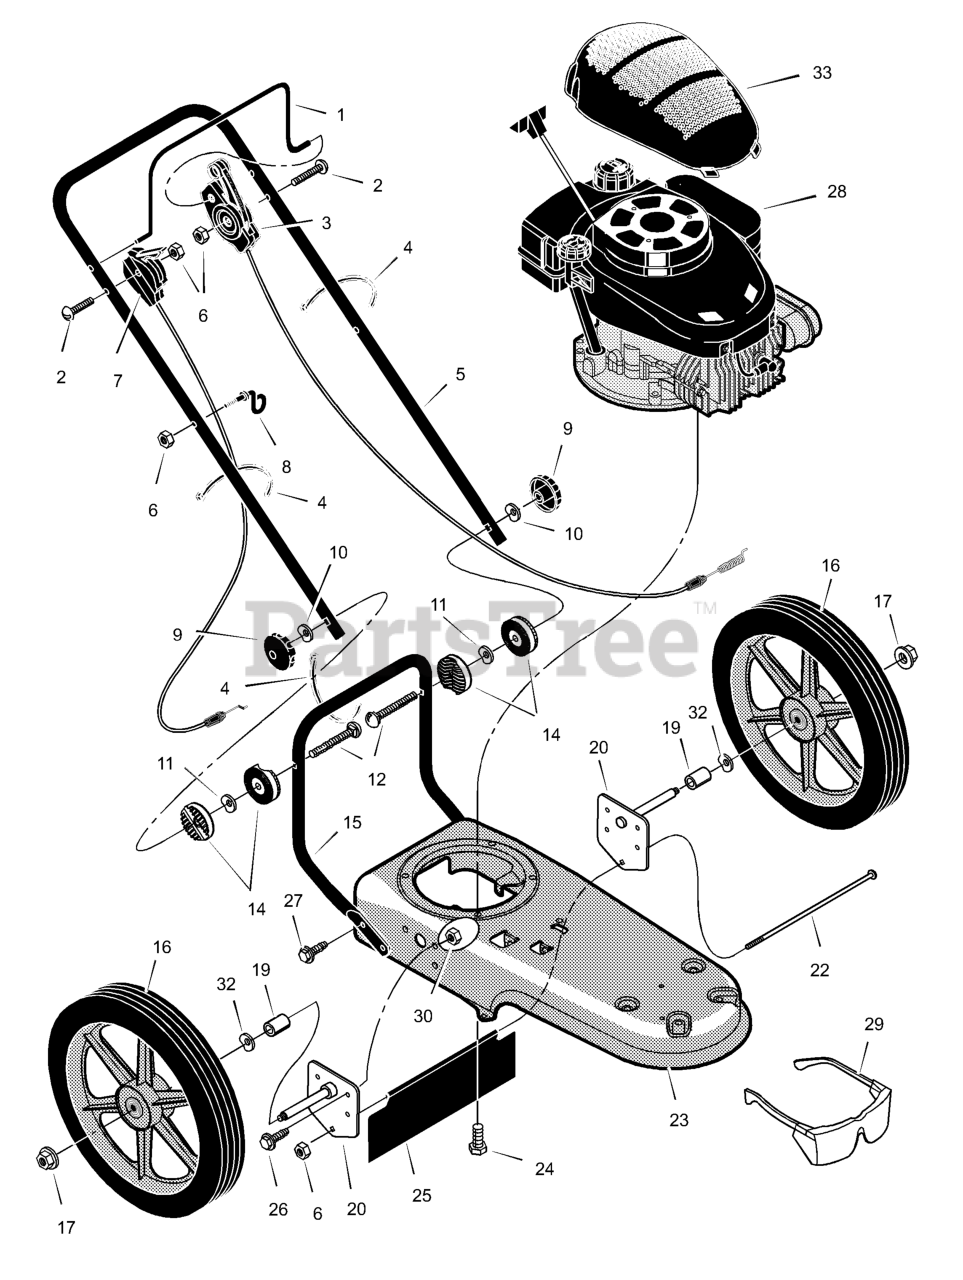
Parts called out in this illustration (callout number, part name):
1	Lever, Stop
3	Cable, Control Latching
4	Tie, Cable
5	Handlebar
6	Nut
7	Control, Throttle
8	Guide, Rope
9	Knob, Handlebar
11	Washer, Spring
14	Pivot, Handlebar
15	Handlebar, Lower
16	Wheel & Tire
17	Nut, Axle
18	Washer, Spring
20	Assembly, Axle & Bracket
22	Bolt, Carriage
25	Shield, Trailing
26	Bolt
28	Engine
29	Glasses, Safety
30	Nut
32	Washer, Spring
33	Shroud, Engine
